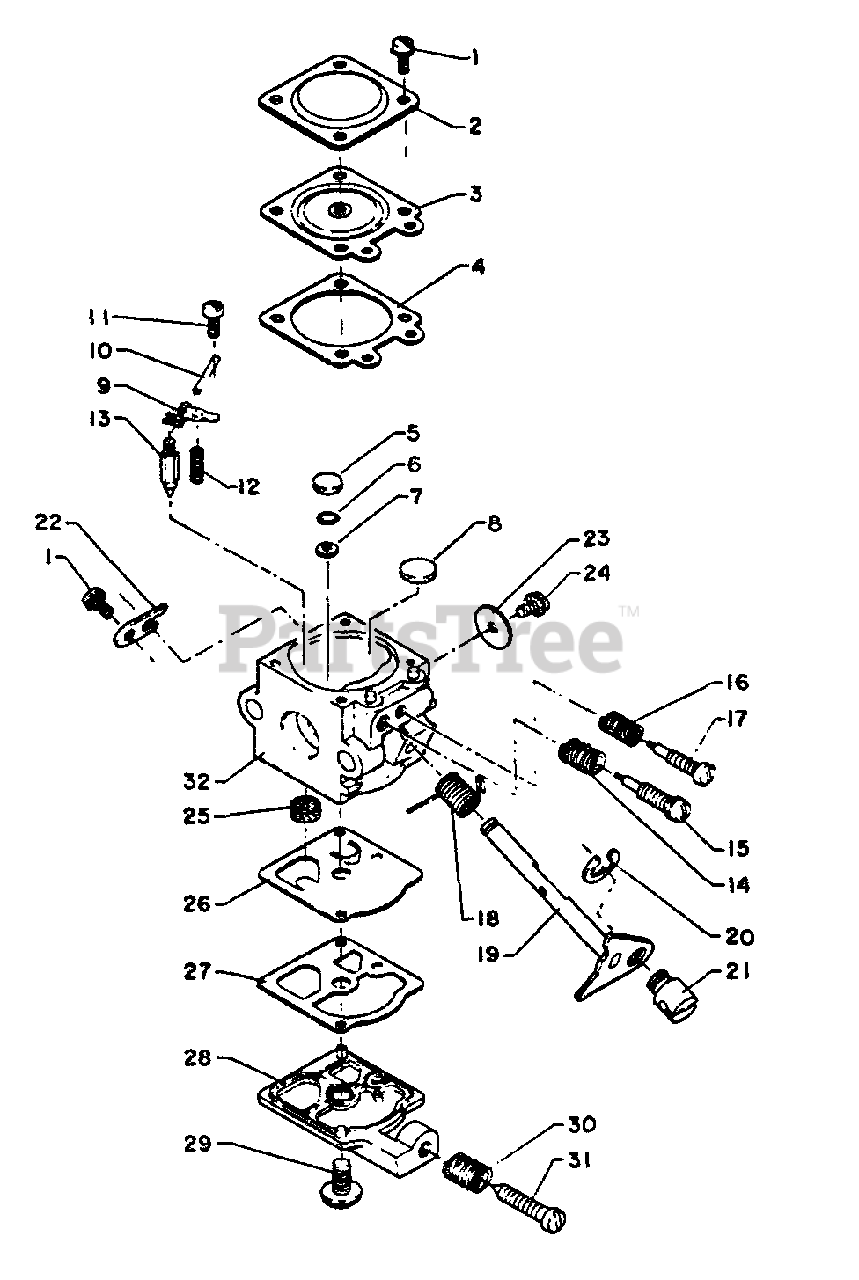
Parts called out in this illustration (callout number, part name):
2	COVER, METERING DIAPHRAGM
3	DIAPHRAGM, METERING
4	GASKET, METERING
5	PLUG, WELCH
6	RING, RETAINING
7	SCREEN, SPARK ARRESTER
8	PLUG, WELCH
9	LEVER, METERING
10	PIN, METERING LEVER
11	SCREW, METERING LEVER PIN
13	VALVE, INLET NEEDLE
14	SPRING, NEEDLE
15	NEEDLE, HIGH SPEED
16	SPRING, NEEDLE
17	NEEDLE, LOW SPEED
18	SPRING, THROTTLE RETURN
19	SHAFT, THROTTLE
20	RING, RETAINING
22	CLIP, THROTTLE SHAFT
23	VALVE, THROTTLE
25	SCREEN, FUEL INLET
26	DIAPHRAGM, PUMP
27	GASKET, FUEL PUMP
28	COVER, FUEL PUMP
31	SCREW, IDLE ADJUST
32	LABEL - GENERATOR
